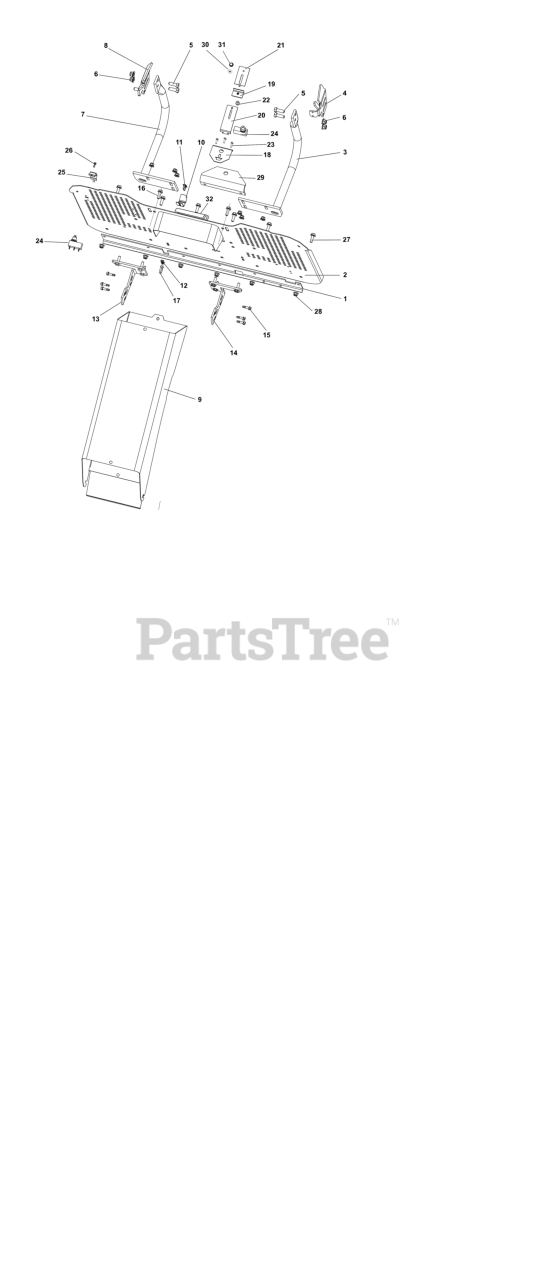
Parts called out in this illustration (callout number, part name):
1	PLATE, Reinforcement
9	CHUTE, Discharge
24	MICROSWITCH
25	SWITCH, Cover
